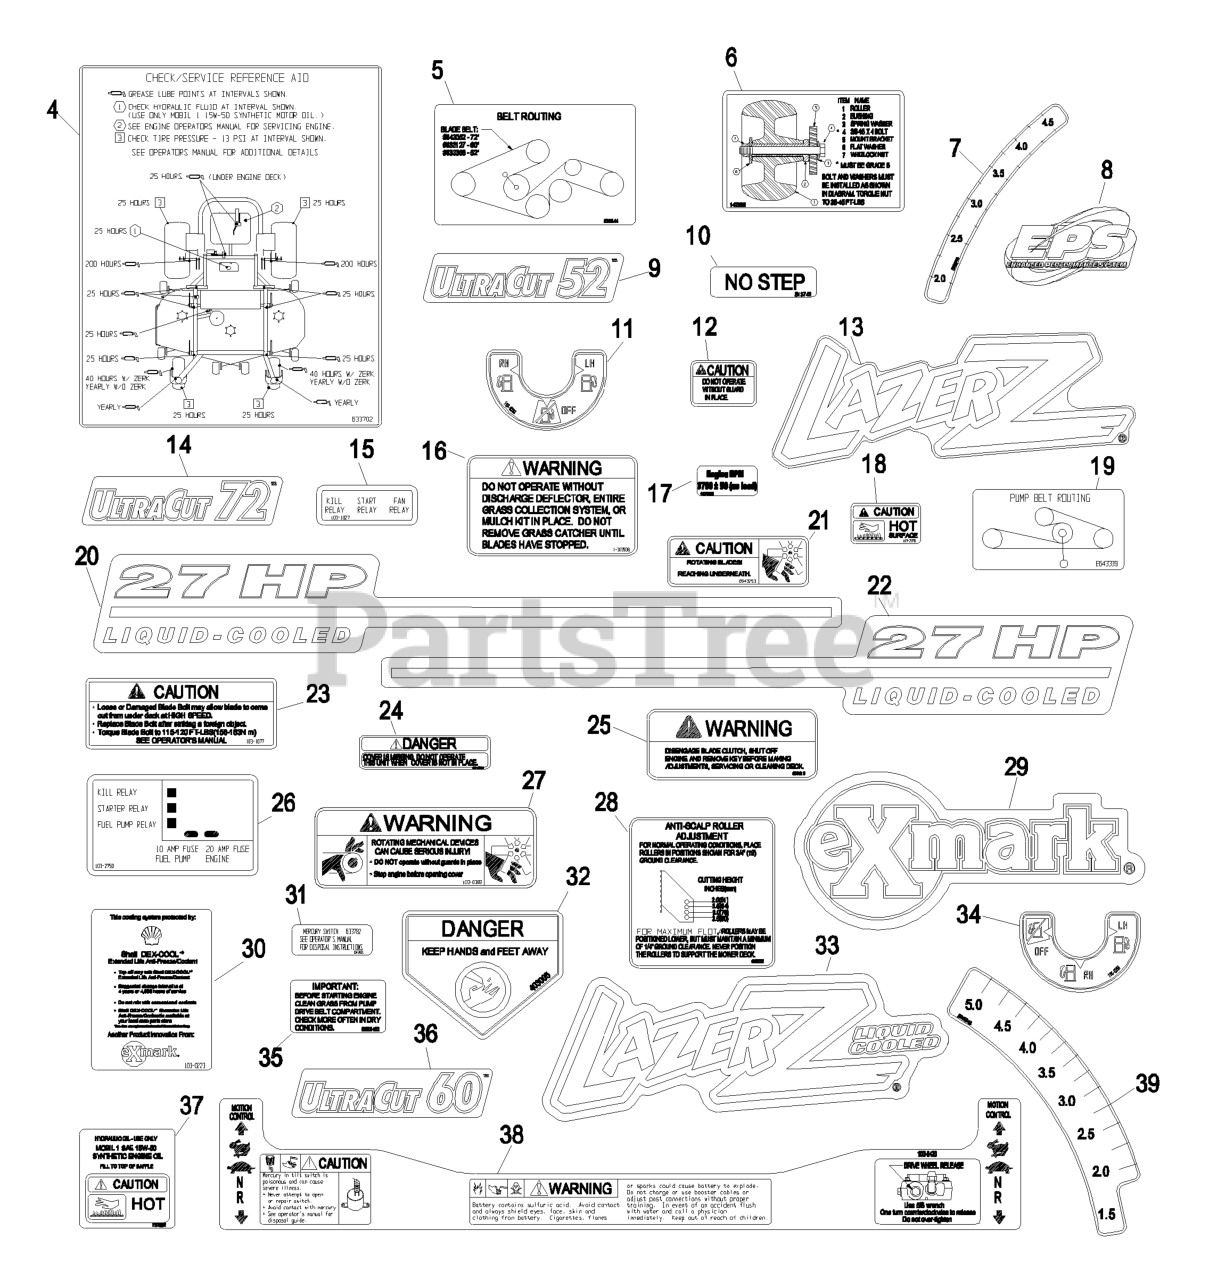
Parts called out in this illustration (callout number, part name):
4	DECAL,CHECK/SERVICE
5	DECAL,BELT ROUTING
6	DECAL,ROLLER MOUNTING
7	DECAL-HEIGHT, DECK
9	DECAL,ULTRACUT 52
10	DECAL,NO STEP
11	DECAL-VALVE, FUEL
12	DECAL-GUARD
13	DECAL,LAZER MODEL
14	DECAL,ULTRACUT 72
15	DECAL-RELAY
16	DECAL-WARNING, DISCHARGE
18	DECAL-CAUTION
19	DECAL-ROUTING, BELT
20	DECAL,HOOD 27LC LH
21	DECAL-FAN, RADIATOR
23	DECAL,BOLT TORQUE
24	DECAL-COVER, MISSING
25	DECAL,WARNING
28	DECAL,ANTISCALP
29	DECAL,EXMARK LOGO
30	DECAL,SHELL COOLANT
31	DECAL-SWITCH, MERCURY
32	DECAL-DANGER
34	DECAL-VALVE, FUEL
35	DECAL-IMPORTANT
36	DECAL,ULTRACUT 60
39	DECAL-HEIGHT, DECK
